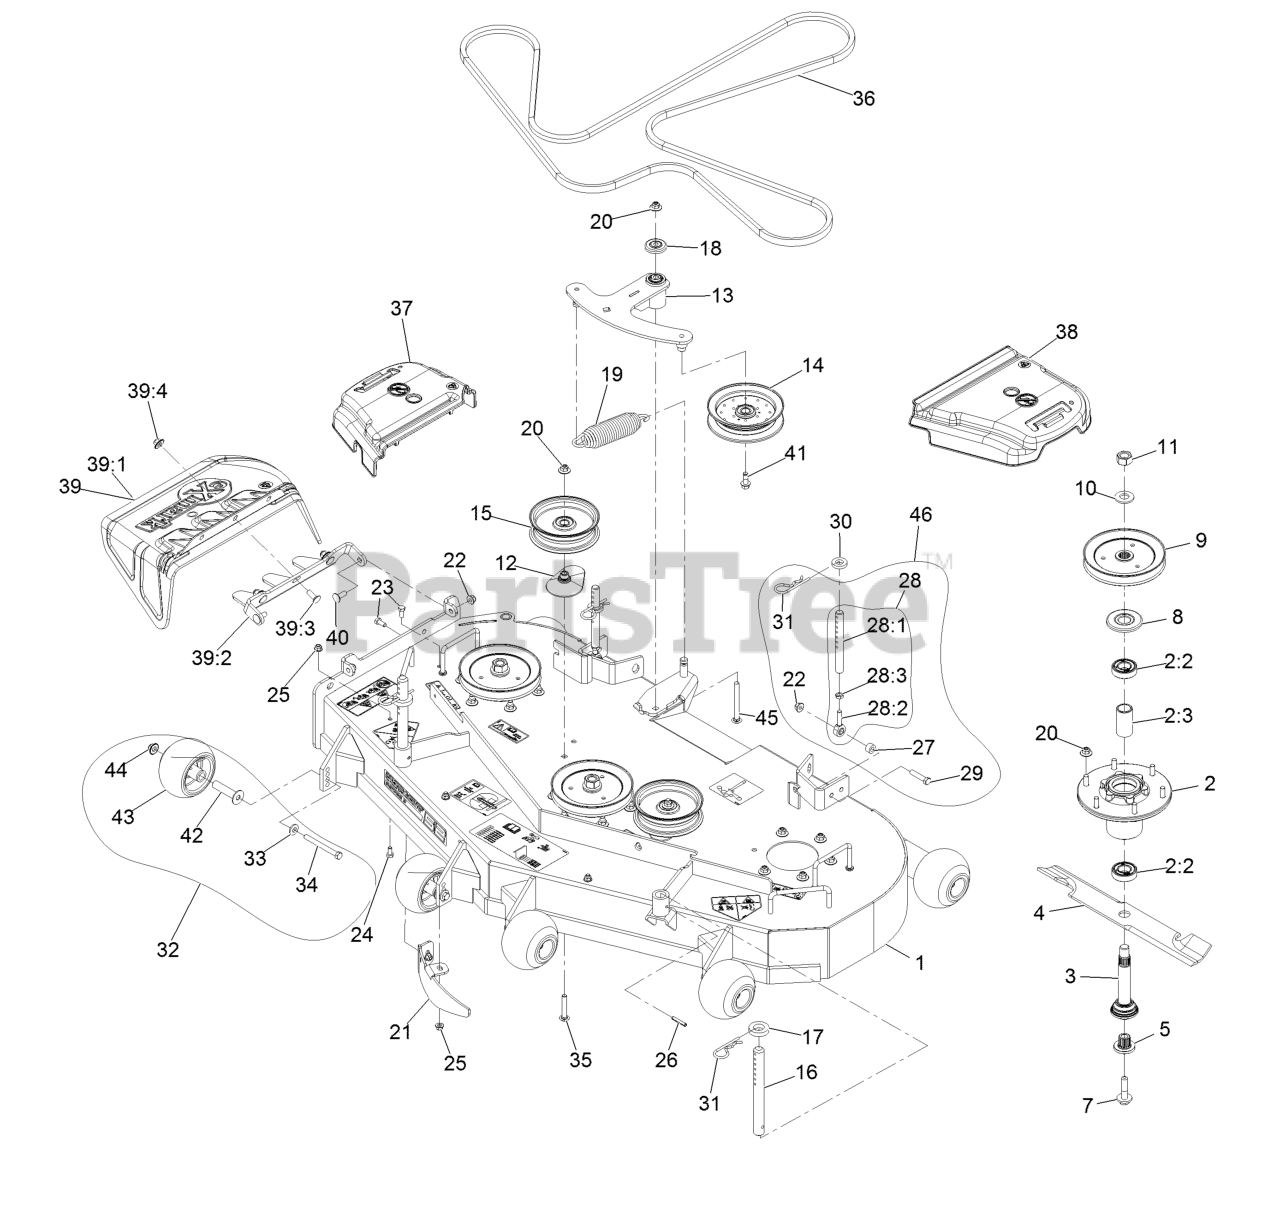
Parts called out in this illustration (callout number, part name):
1	ASM, Deck W/ Decals, 52"
2	ASM-Cutter Hsg With Bearings
2:2	Bearing-Ball
2:3	Spacer-Bearing
3	ASM-Spindle And Seal
4	Blade, Solid
4	Blade, Low Lift
4	Blade, Mulching
4	Blade-Notched
4	Blade-Extreme 2, 18.00"
5	Bushing, Splined
7	Screw-Sems 1/2-20 X 2.19
8	Guard,Bearing Top .989
9	Sheave,Blade Drive 6.50
10	Washer-Spring Disc 3/4
11	Nut-Hex
12	Spacer-Pulley
13	ASM, Deck Idler
14	Idler-Pulley, Flanged
15	Idler-Pulley, Flat
16	Rod, Deck Support
17	Spacer-Deck Support
18	Guard-Top
19	Spring-Extension
20	Nut-Nyloc 3/8-16 Flg
21	Baffle, Dogleg
22	Nut-Nyloc 3/8-16 Flg
23	Screw-HH 5/16-18 X 3/4
24	Screw-HH 5/16-18 X 5/8
25	Nut-Nyloc 5/16-18 Flg
26	Rollpin 1/4 X 1 1/2
28	Link Assy
28:1	Link, Rear Deck Support
28:2	Balljoint
28:3	Nut-Jam 3/8-24
29	Screw-HH 3/8-16 X 1 3/4
30	Spacer-Blade Drive
31	Hairpin-Cotter #206
32	Kit, Anti-Scalp Roller
33	Washer-Spring Disc 3/8
34	Screw-HH 3/8-16 X 3 3/4 GR 8
35	Bolt-Carriage 3/8-16 X 2 1/4
36	Belt, Deck
37	Cover-Belt, RH
38	Cover-Belt, LH
39	ASM, Discharge Chute
39:1	Chute, Discharge
39:2	Bracket, Discharge Chute
39:3	Bolt-Carriage 3/8-16 X 1
39:4	Nut-Nyloc 3/8-16 Flg
40	Bolt-Carriage 3/8-16 X 1
41	Screw-Hfh
42	Axle, Roller
43	Roller-Anti-Scalp
44	Nut-Nyloc 3/8-16 Flg
45	Bolt-Carriage 3/8-16 X 3 3/4
46	Kit, Support Link W/Pin
